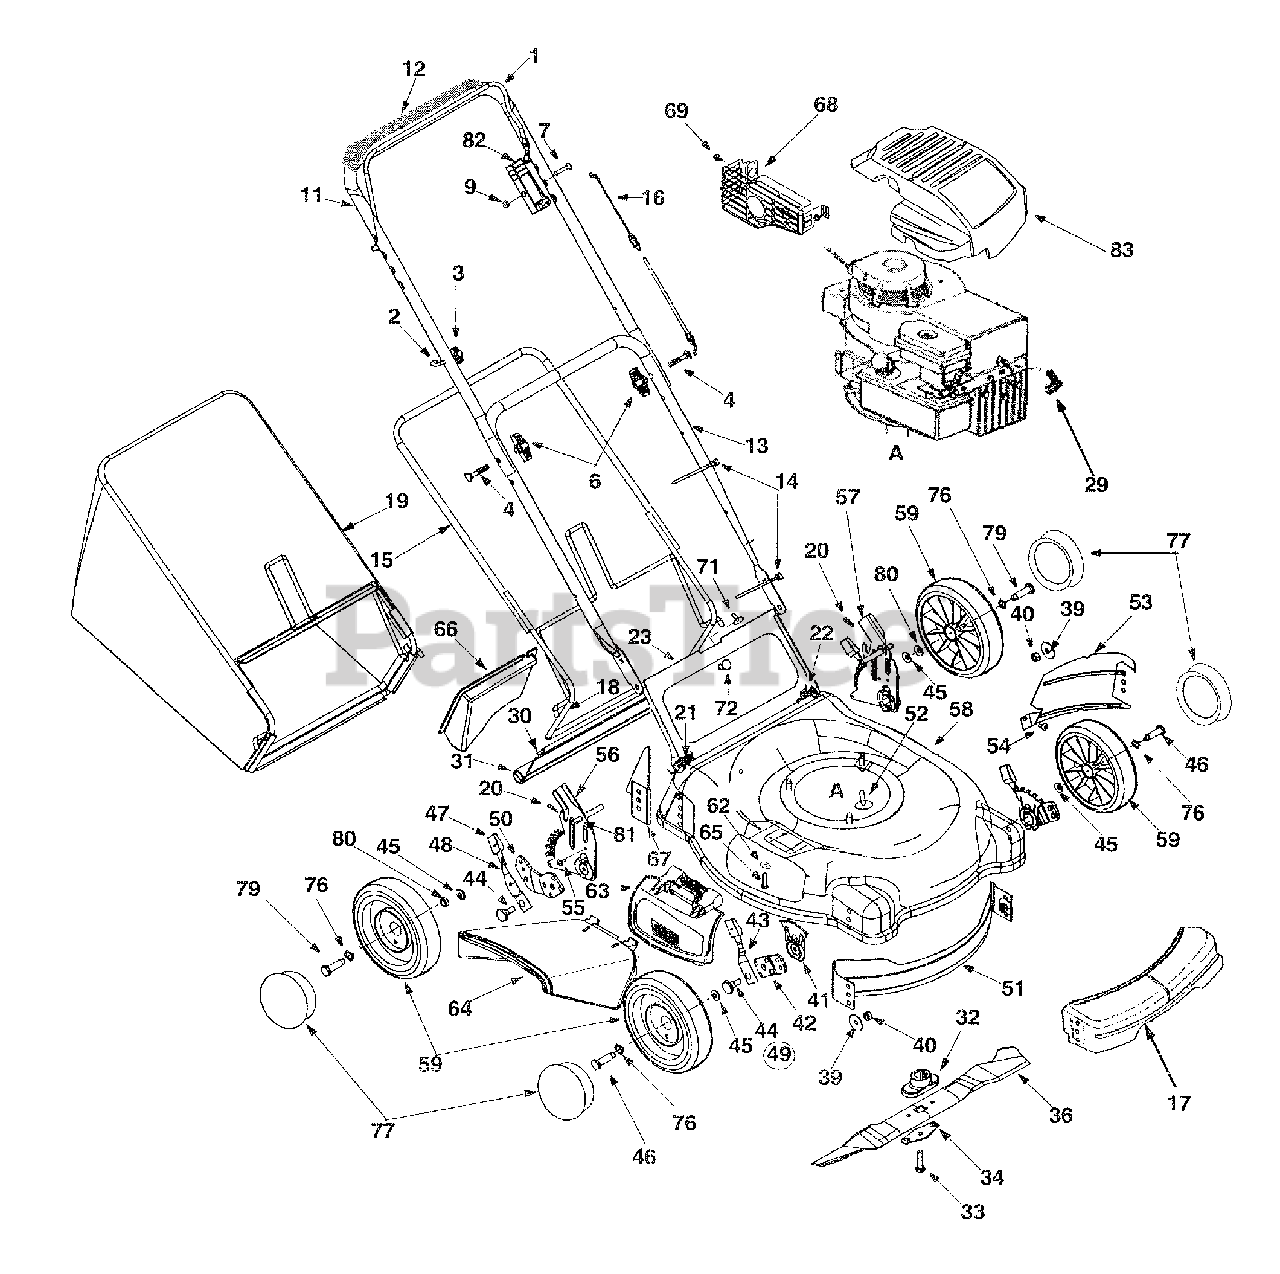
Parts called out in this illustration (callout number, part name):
1	Control Handle Assembly
2	Rope Guide
3	Handle Knob 1/4-20 Thd.
4	Carriage Bolt 5/16-18 x 2" Lg.
6	Hand Knob
7	Oval C-Sunk Mach. Scr.
9	Hex L-Nut 1/4-20 Thd.
14	Cable Tie
16	Control Cable - 43"
17	Front Cover: Black
20	Int. Cotter Pin 5/16" Dia.
21	Door Spring - R.H.
22	Door Spring - L.H.
30	Wire Rod
31	Rear Flap
32	Blade Adapter
33	Hex Bolt 3/8-24 x 1.5" Lg.
34	Blade Bell Support
36	21" Mulching Blade
39	Bell-Wash. .39" I.D. x 1.38"
40	Hex Nut 3/8-16 Thd.
41	Height Adj. Plate
43	Front Spring Lever Ass'y. w/Knob
44	Shld. Bolt .5" Dia. x .357"
45	Bell-Wash. .38" I.D. x .88" O.D.
46	Front Axle Bolt
47	Spring Lever Knob
48	Rear Spring Lever
49	Height Adj. Assy. Comp. - RH
50	Pivot Bar R.H.
54	Torx Mach AB-Tap Scr. 1/4 x .62"
55	HexInd Wash. Scr. 1/4-14: .625
56	Handle Brkt. Ass'y.-RH
57	Handle Brkt. Ass'y.-LH
62	Bell-Washer 1/4" I.D.
63	Hinged Mulching Plug
64	Chute Deflector: Side Discharge
65	Hex Hd Self-Tp Scr. 1/4-20 x .5" L.
66	Mulching Baffle Plug
68	Muffler Guard
69	Hex Washer Head Screw
71	Truss Scr. #10-24 x .38" Lg.
76	Wave Washer
77	Hub Cap - Rad. Spoke - Beige
79	Rear Axle Bolt
80	Spacer
82	Control Housing w/o Lever
83	Engine Shroud
